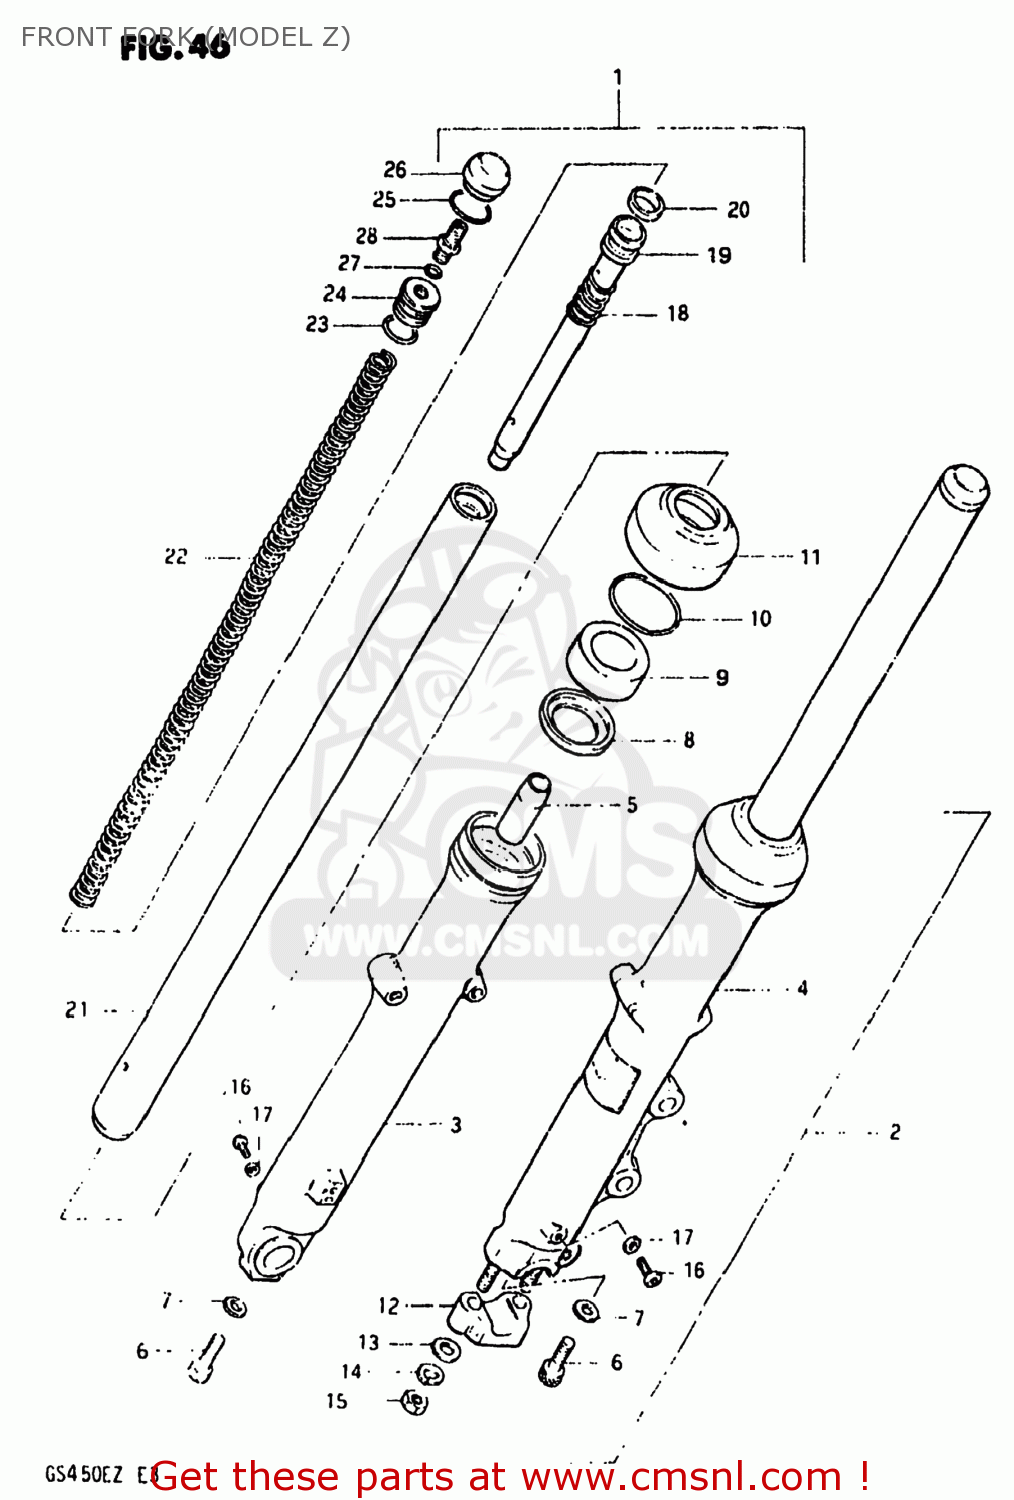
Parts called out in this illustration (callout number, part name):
1	DAMPER ASSEMBLY,RIGHT
2	DAMPER ASSEMBLY,LEFT
3	TUBE,FORK,OUTER,RIGHT
4	TUBE,FORK,LEFT,OUTER
5	PIECE,OIL LOCK
6	BOLT(8X27)
7	GASKET (NAS)
8	SPACER,OIL SEAL
9	OIL SEAL,FRONT FORK
10	RING,OIL SEAL STOPPER
11	DUST SEAL
12	HOLDER,AXLE
13	WASHER
14	LOCK WASHER
15	NUT
16	SCREW 4X6
17	GASKET (NAS)
18	SPRING,REBOUND
19	CYLINDER,FRONT FORK
20	RING,PISTON
21	TUBE,FORK,INNER
22	SPRING
23	O RING
24	SEAT,SPRING
25	RING,STOPPER
26	CAP,FRONT FORK
27	O-RING
28	VALVE,AIR
